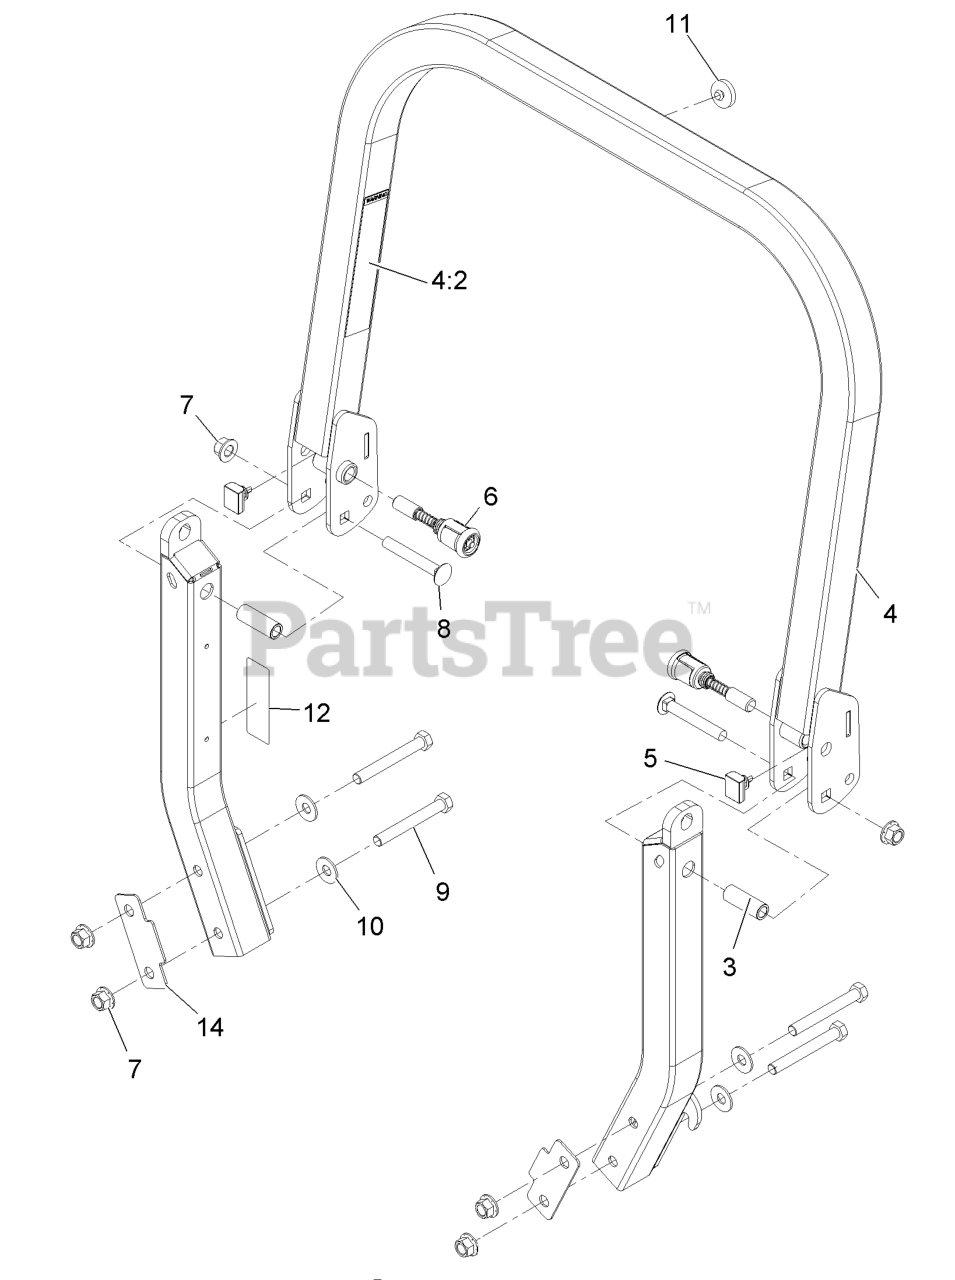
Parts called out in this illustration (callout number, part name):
4	UPPER ROPS ASM
4:2	DECAL-WARNING, FOLDING RO
5	BUMPER-ROPS
6	PIN-SPRING
7	Nut-Lock 1/2-13
8	SCREW-CARR
9	SCREW-HH
10	WASHER-SPRING
11	BUMPER-PUSH-IN, RUBBER
12	DECAL-CAUTION
